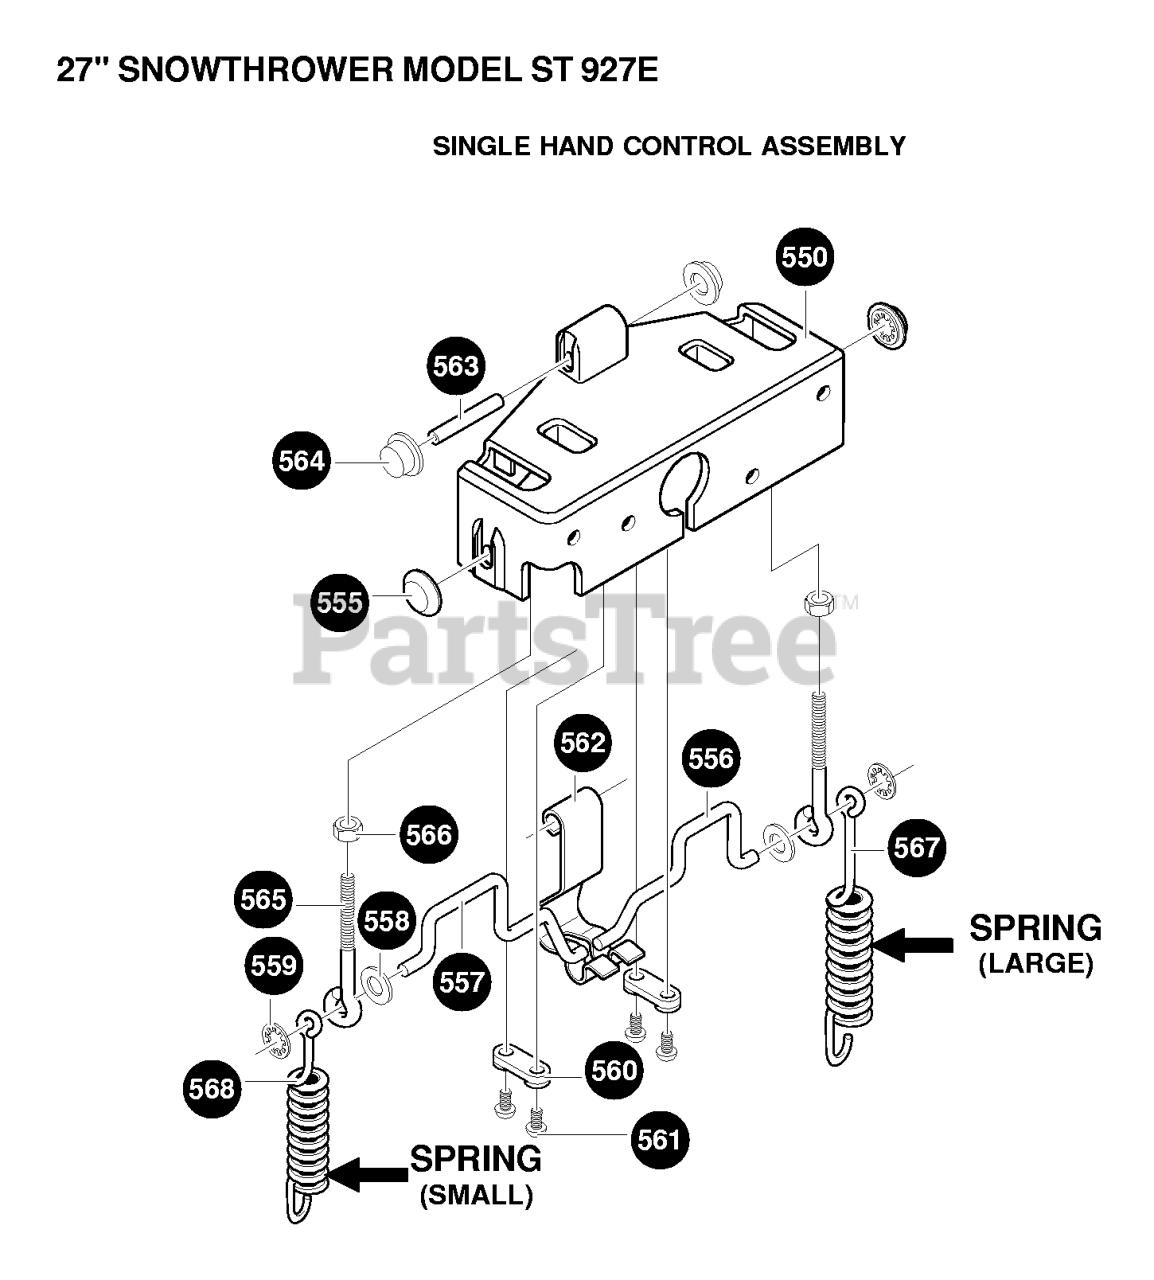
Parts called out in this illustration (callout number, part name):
550	HOUSING, SINGLE HAND CONTL
555	NUT, PUSH ON CAP .312 OD
556	CAM/LATCH LH
557	CAM/LATCH RH
558	WASHER, FLAT .344X .69X.
559	RING, RETAINING
560	CLAMP, SHC CAM FRAME MTD
561	SCREW, #8 X .75 PANTAPPLAST
563	PIN, SPRING PIVOT
564	NUT-PUSH ON 3/8"
565	EYE-BOLT, 10-24X2.50
566	NUT, #10-24 REGHEX
567	SPRING, DRIVE CLUTCH
568	SPRING, AUGER CLUTCH
